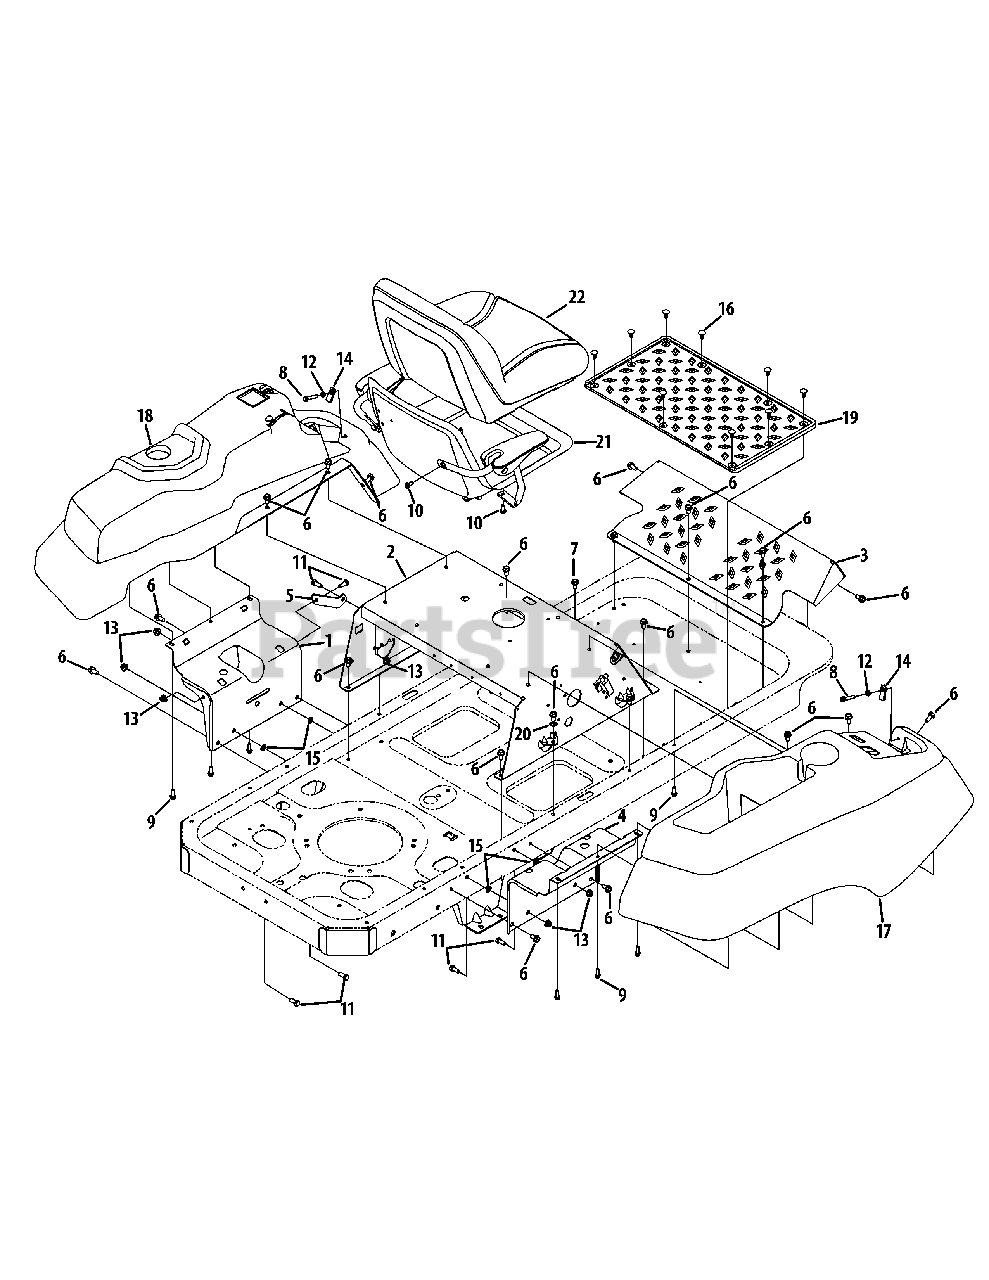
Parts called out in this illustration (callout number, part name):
1	Console Bracket Assembly
2	Seat Frame Assembly
3	Foot Rest Bracket
4	Console Mount Bracket
5	Fuel Tank Support Bracket
6	Hex Washer Screw, 5/16-18 x .750
7	Hex Washer Screw, 5/16-18 x .625
8	Hex Washer Screw, 1/4-20 x 1.500
9	Hex Washer Screw, 1/4-15 x 0.750
10	Screw, 5/16-18 x .750
11	Hex Screw, 5/16-18 x .75
12	Jam Nut, 1/4-20
13	Flange Lock Nut, 5/16-18
14	Speed Nut, 1/4-20
15	Speed Nut, .3125
16	Ratchet Clip, .250
17	RH Console
18	LH Console
19	Foot Pad
20	Lock Washer, 3/8
21	High-Back Seat Arm
22	High-Back Seat
